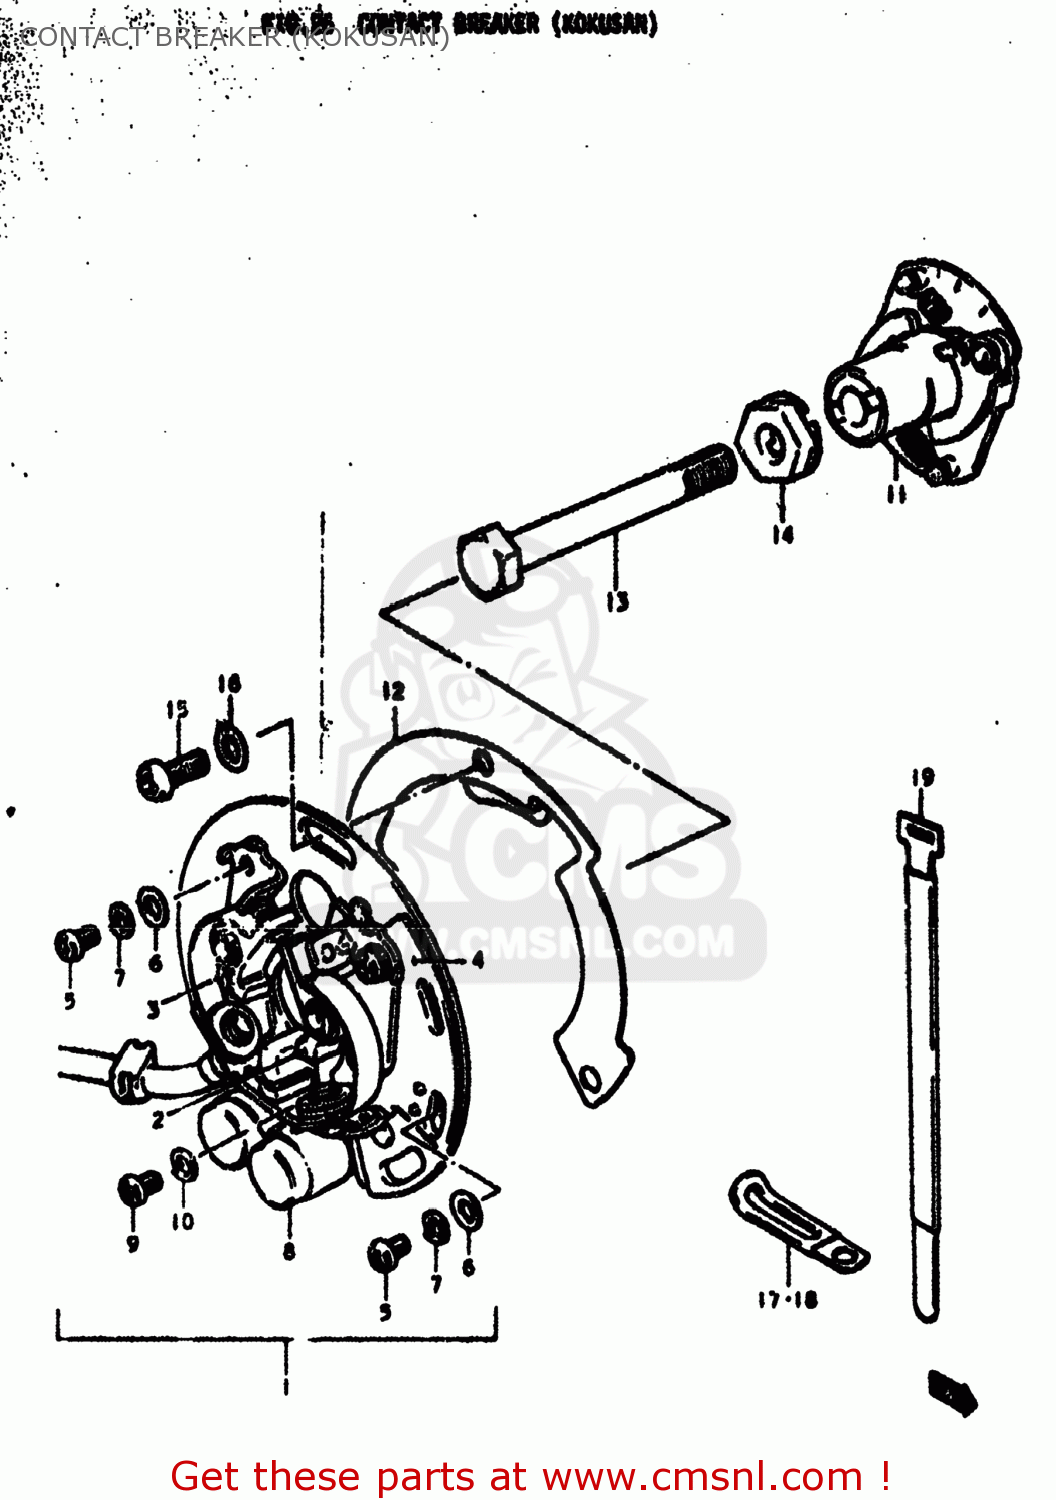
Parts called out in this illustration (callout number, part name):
1	BREAKER ASSEMBLY,CONTACT
2	POINT ASSEMBLY,CONTACT
3	POINT ASSEMBLY,CONTACT
4	PLATE,CONTACT POINT
5	SCREW
6	WASHER
7	LOCK WASHER
8	CONDENSER
9	SCREW
10	LOCK WASHER
11	GOVERNOR ASSEMBLY
12	PLATE,IGNITION TIMING
13	BOLT
14	WASHER
15	SCREW(5X12)
16	WASHER
17	CLAMP L:35
18	CLAMP
19	CLAMP
